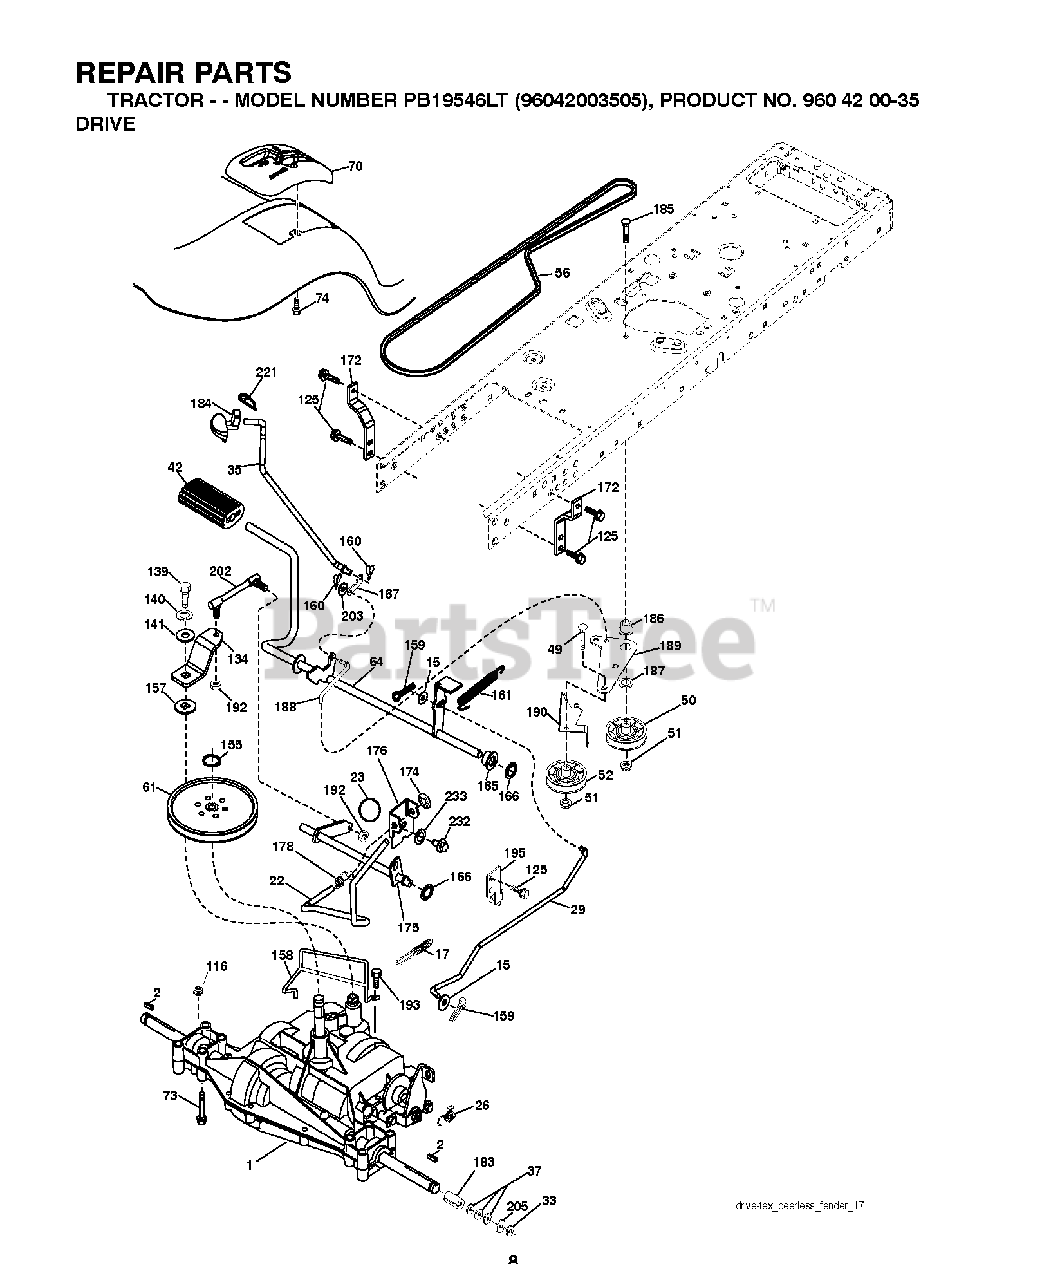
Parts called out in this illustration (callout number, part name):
2	SQUARE KEY
17	SPRING.BRAKE.PEERLESS.TEX
22	ROD.SHIFT.FENDER.TLT.2006
23	KNOB.DELUXE.(PISTOL.GRIP).BLAC
29	ROD.BRAKE.PEERLESS
33	E-RING LT
35	ROD.BRAKE.PARKING.LT.T
49	BOLT
50	IDLER.FLAT.910.OFFSET
51	NUT LOCK FLG 3/8-16 UNC
52	IDLER.V-GROOVE.910.OFFSET
56	V-BELT.TRACTOR.DRIVE.P
61	PULLEY TRANS
64	SHAFT.ASM.PEDAL.BRAKE.
70	CONSOLE.SHIFT.STL.6SP.BLACK.T
73	BOLT HEX 5/16-18 GR 5
74	SCREW.HI-LO.CONSOLE
116	NUT LOCK HEX FLANGE 5/16-18
125	SCREW
134	ARM SHIFT
139	Bolt, 1/4-20 unf Grade 8 w/Patch
140	LOCKWASHER
141	WASHER LT
155	RETAINING RING LT
157	WASH-SHFT PLT LT
158	KEEPER.PMS.18/20.D4365
159	COTTER PIN
160	RETAINER CLIP
161	SPRING, RETURN LT
165	BUSHING.SHAFT.BRAKE.HAND
166	NUT.PUSH.625
167	LATCH.BRAKE.SPRING
172	STRAP.TRQ.LH.GEAR.DRIV
174	NUT.PUSH.500.2006
175	SHAFT ASM SHIFT
176	ARM.CLEVIS.ROD.SHIFT
178	SPRING.SHIFT.GT2006
183	SPACER AXLE
184	HANDLE.PARKING.BRAKE.LTTEX.667
186	SPACER.RETAINER
187	WASHER 12/32X2X10GA
188	LINK.CLUTCH.GROUND.DRIVE
189	BELLCRANK.GROUND.DRIVE.TEX.
190	KEEPER.BELLCRANK.DRIVE
192	NUT LOCK CENTER 1/4 -28 FNTHD
193	SCREW 5/16"
195	BRKT.ROD.BRAKE.PEERLES
202	LINK.SHIFT.PMST.18" (SPG1286)
203	WASHER
221	RETAINER.SPRING.CLIP.H
232	BOLT FIN HEX 7/16-14 X 1
233	WASHER SERRATED
